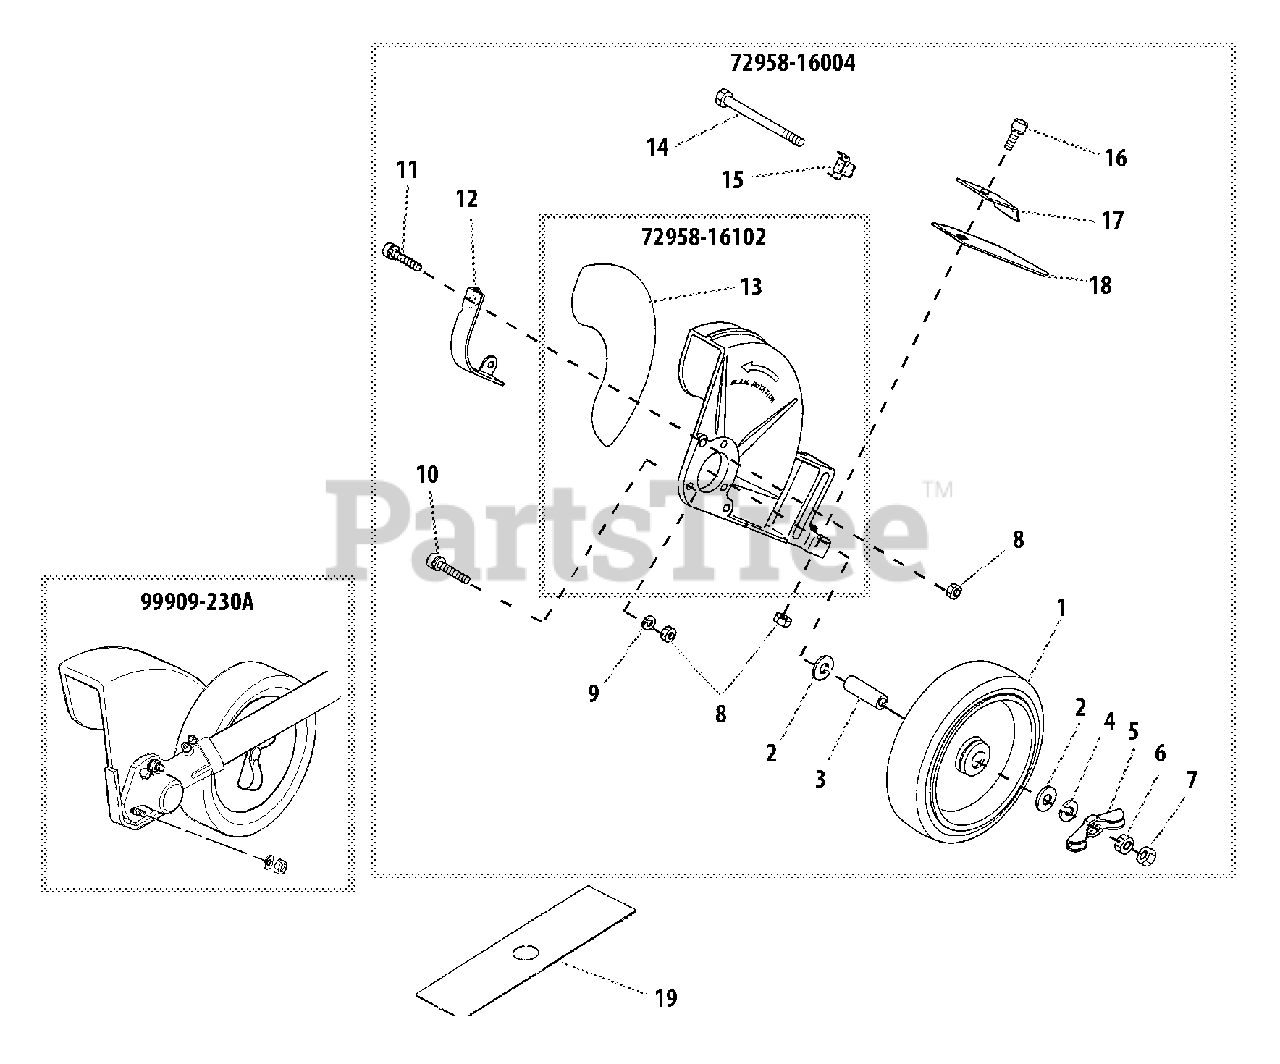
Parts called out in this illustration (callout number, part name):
1	WHEEL
2	WASHER
3	COLLAR
4	LOCKWASHER - 8
5	WINGNUT
6	NUT - 8
7	LOCKNUT
9	LOCKWASHER - 5
10	SCREW - 5X25
11	SCREW - 5X12
12	PROTECTOR
13	LABEL - TRADE
14	BOLT - 8X90
15	BRACKET
16	SCREW - 5X16
17	PLATE
18	DEFLECTOR
19	BLADE, EDGER
72958-16004	GUARD ASSY
72958-16102	GUARD
99909-230A	GEAR CASE KIT
